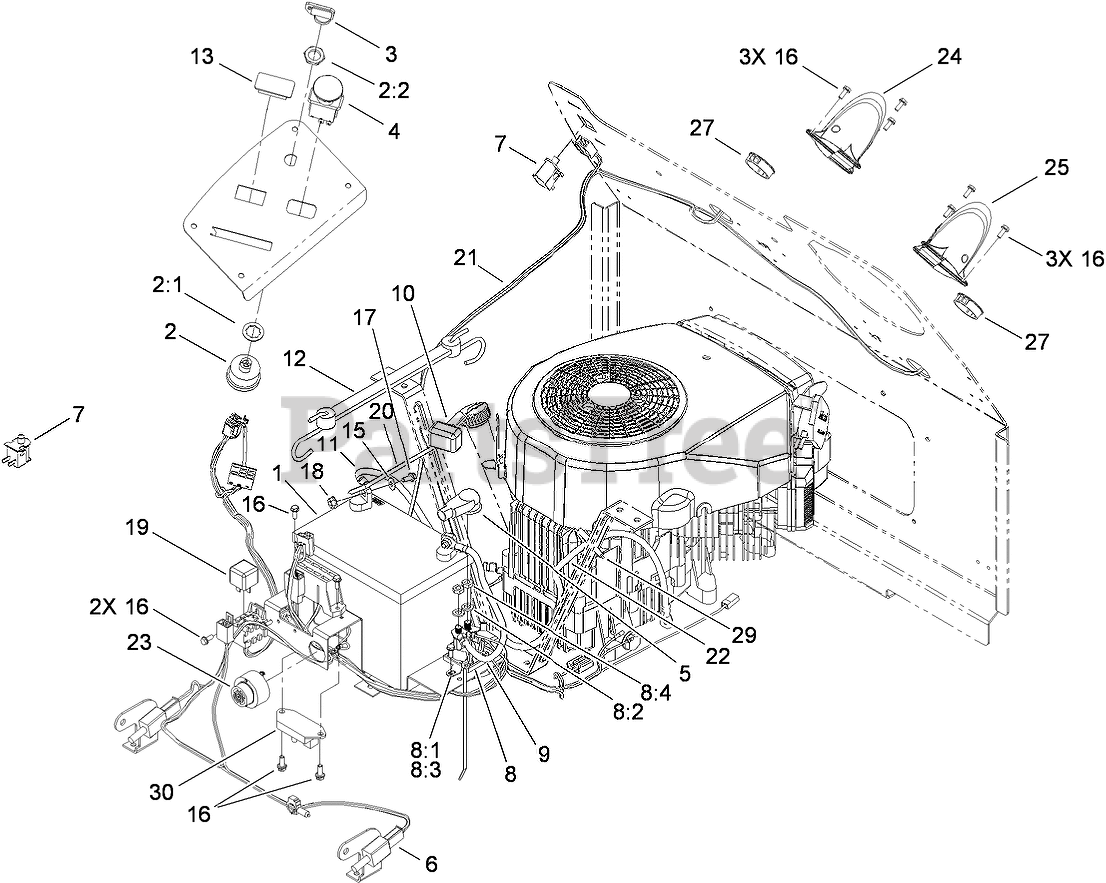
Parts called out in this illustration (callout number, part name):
1	BATTERY
2	Key Switch ASM
2:1	WASHER-TOOTH, INTERNAL
2:2	NUT-HH
3	KEY-IGNITION
4	SWITCH-PTO
5	BOOT-TERMINAL
6	SWITCH
7	SWITCH-BAIL
8	SWITCH-SOLENOID
8:1	WASHER-LOCK
8:2	WASHER-LOCK
8:3	NUT-HEX
8:4	NUT-JAM
9	CABLE-BATTERY, POSITIVE
10	BOOT-INSULATOR, TERMINAL
11	CABLE-NEGATIVE, BLACK
12	HOLDDOWN-BATTERY
13	PLUG-HOLE
15	WASHER-FLAT
16	SCREW-TAPTITE
17	SCREW-HH
18	NUT-HF
19	RELAY
20	TIE-CABLE
21	HARNESS-WIRE, KAWASAKI
22	WIRE-21 INCH
23	ALARM-TONE, DUAL
24	BAG SENSOR ASM
25	BAG SENSOR ASM
27	BUSHING-HARNESS, WIRE
29	CLAMP-HOSE
30	MODULE-DELAY
